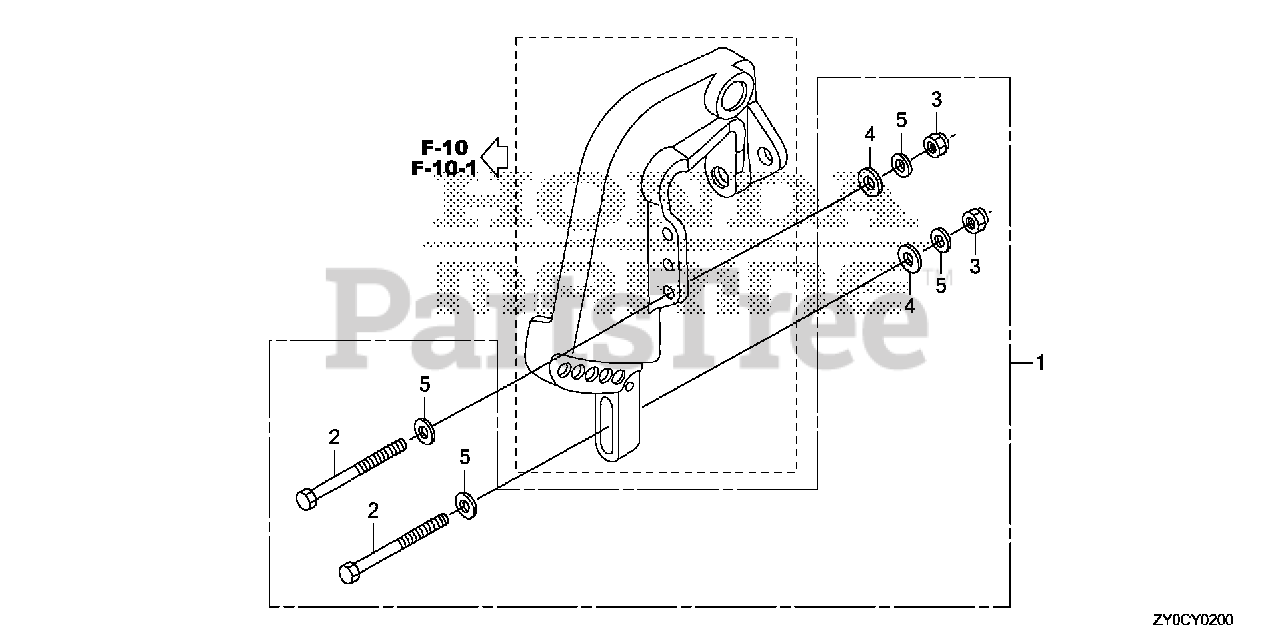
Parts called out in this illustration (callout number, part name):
1	INSTALLATION KIT, OUTBOARD
2	BOLT, HEX. (10X100)
3	NUT, SELF-LOCK (10MM)
4	WASHER, PLAIN (10MM)
5	WASHER, PLAIN (10MM)
